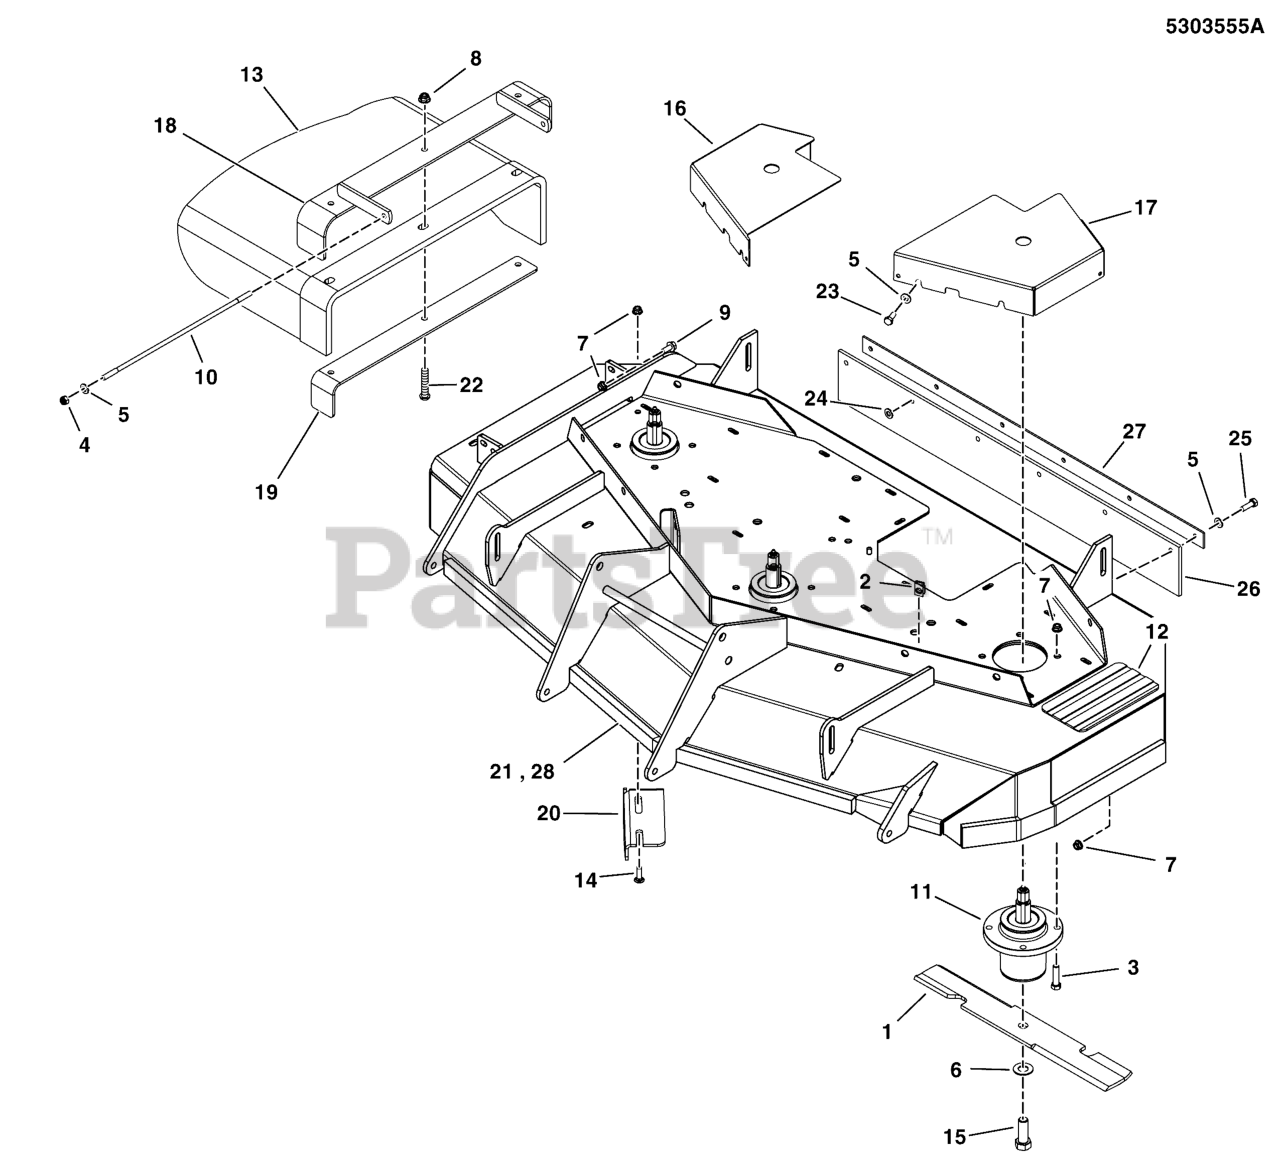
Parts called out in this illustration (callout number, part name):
1	BLADES, SET OF THREE (3); 16.25 X.25 X 2.5, 1 X 3.5
2	BODY CLIP, 5/16-18-7GA MATERIAL
3	BOLT, 5/16-18 X 1 1/4 FLANGE
4	NUT, 5/16-24 HEX NYLON LOCK
5	WASHER, 5/16" SAE
6	WASHER, 5/8 GRADE 8, YZ
7	NUT, 5/16-18 HEX NYLOCK FLANGE
8	NUT, 3/8-16 HEX NYLOCK FLANGE
9	BOLT, 5/16-18 X 3/4 GD5
10	ROD, 5/16 X 13.75, TBE, CZ
11	ASSM, SPINDLE, LOW PROFILE
12	SAFETY WALK, 4.00 X 7.50
13	CHUTE, RUBBER DISCHARGE
14	BOLT, 5/16-18 X 3/4, CARRIAGE
15	BOLT, 5/8-11 X 1-3/4 GD8
16	PLATE, DECK GUARD, RH - RED
17	PLATE, DECK GUARD, LH - RED
18	WELD, MOUNT, DISCHARGE CHUTE - BLK
19	SUPPORT, DISCHARGE CHUTE - BLK
20	PLATE, DEFLECTOR - BLK
21	DECK SHELL W/ DECALS, 48, S150XT-DOM (5413100D)
22	BOLT, 3/8-16 X 1-1/2, CARRIAGE, GD5, CZ
23	BOLT, 5/16-18 X 1 GD5 YZ
24	5/16 PUSH-ON NUT RETAINER, STL, CZ
25	BOLT, 5/16-18 X 1 GD5 YZ
26	FLAP, RUBBER, 48"
27	PLATE, SUPPORT, 48 - BLK
28	DECK SHELL W/DECALS,48,S150XT,5414848D
